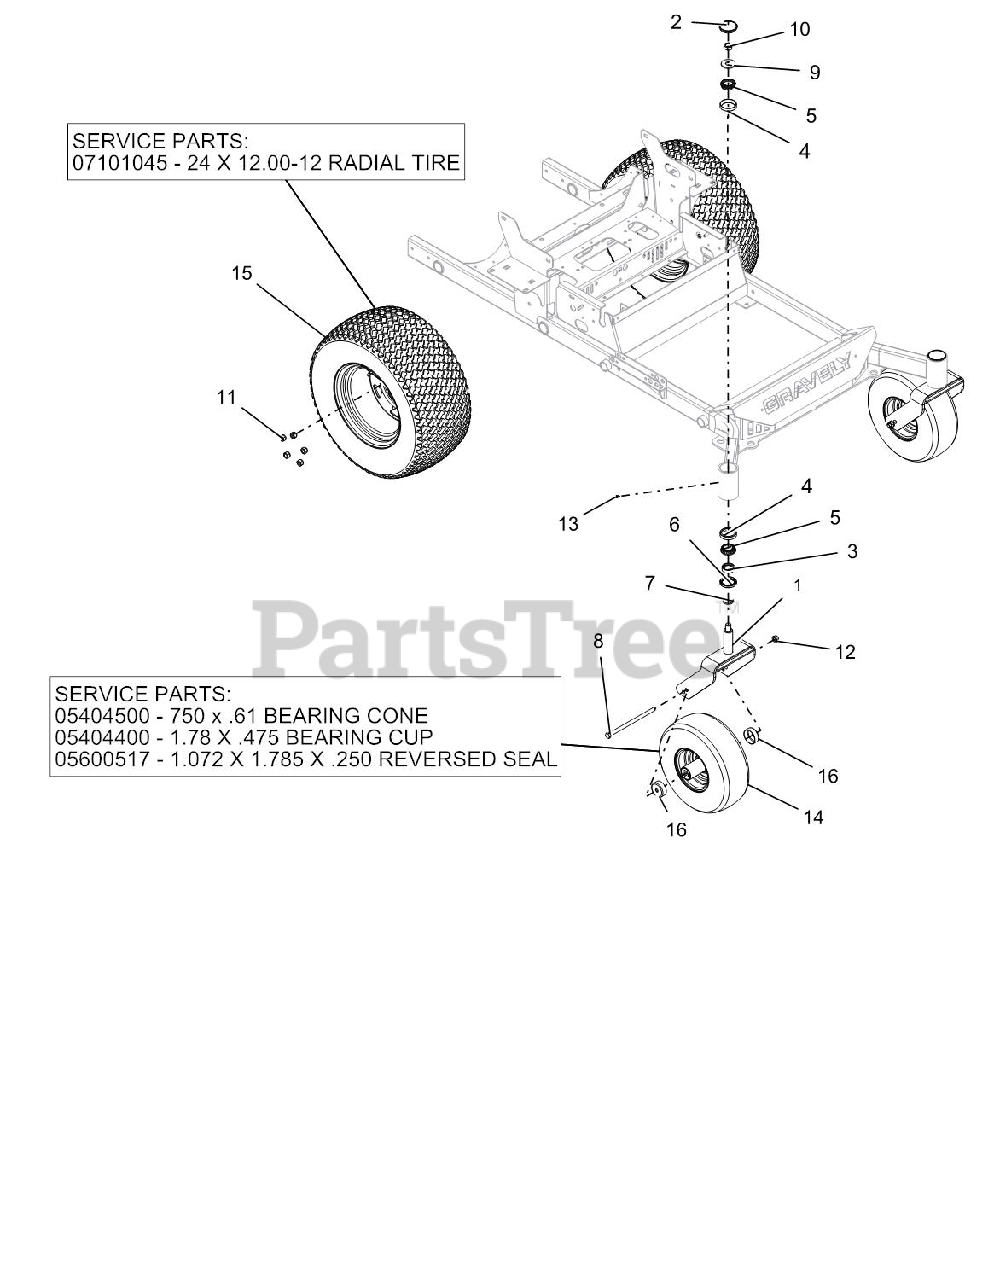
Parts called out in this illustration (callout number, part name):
1	WMT, CASTER FORK - RED
2	CAP, DUST
3	SPCR, FRONT CASTER FORK
4	BRG, CUP 2.328 X .465
5	BRG, CONE 1.250 X .660
6	SEAL, OIL 1.75 X 2.332 X .312
7	O-RING, .139 W X 1.234 ID
8	BLT-HEX .50-13X9.00 GR5 YWZC
9	WSHR-FL-STL.812X2.00X.148YWZC
10	NUT-LK-TOP-JAM .75-16 YWZC
11	NUT, LUG .500-13
12	NUT, LK-TOP-FLG .50-13 YWZC
13	FITTING, .250-28 FLUSH MOUNT GREASE
14	750 X .61 BEARING CONE
14	1.78 X .475 BEARING CUP
14	1.072 X 1.785 X .250 REVERSED SEAL
14	ASM, TIRE/WHEEL 15 X 6.00-6 SEMI
15	24 X 12.00-12 RADIAL TIRE
15	ASSM TIRE\WHEEL, 24 X 12.00 - 12 RADIAL
16	SHIELD, WHEEL BEARING
